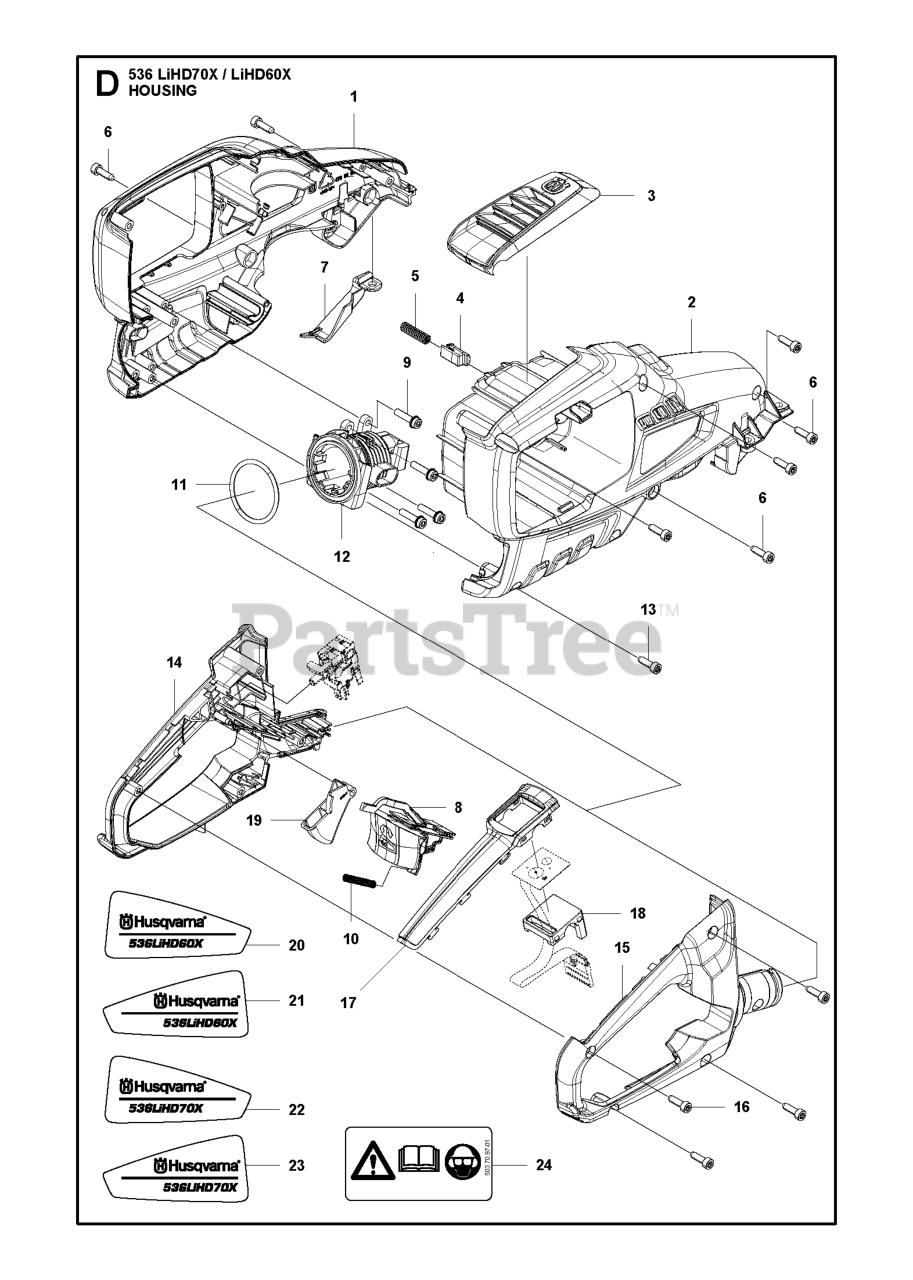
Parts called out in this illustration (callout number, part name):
1	CHASSIS LEFT
2	CHASSIS RIGHT
3	COVER CHASSIS
4	PUSH BUTTON
5	SPRING
7	COVER WIRING
8	LOCKING BUTTON
9	SCREW IHSCFT
10	RECOIL SPRING RECOIL SPRING RE
11	O-RING
12	HANDLE HOLDER
13	SCREW
14	REAR HANDLE LEFT
15	REAR HANDLE RIGHT
16	SCREW
17	FRAME KEYPAD
18	BRACKET KEYPAD
19	THROTTLE CONTROL
20	DECAL PRODUCT DECAL 536LIHD60X
21	DECAL PRODUCT DECAL 536LIHD60X
22	DECAL PRODUCT DECAL 536LIHD70X
23	DECAL PRODUCT DECAL 536LIHD70X
